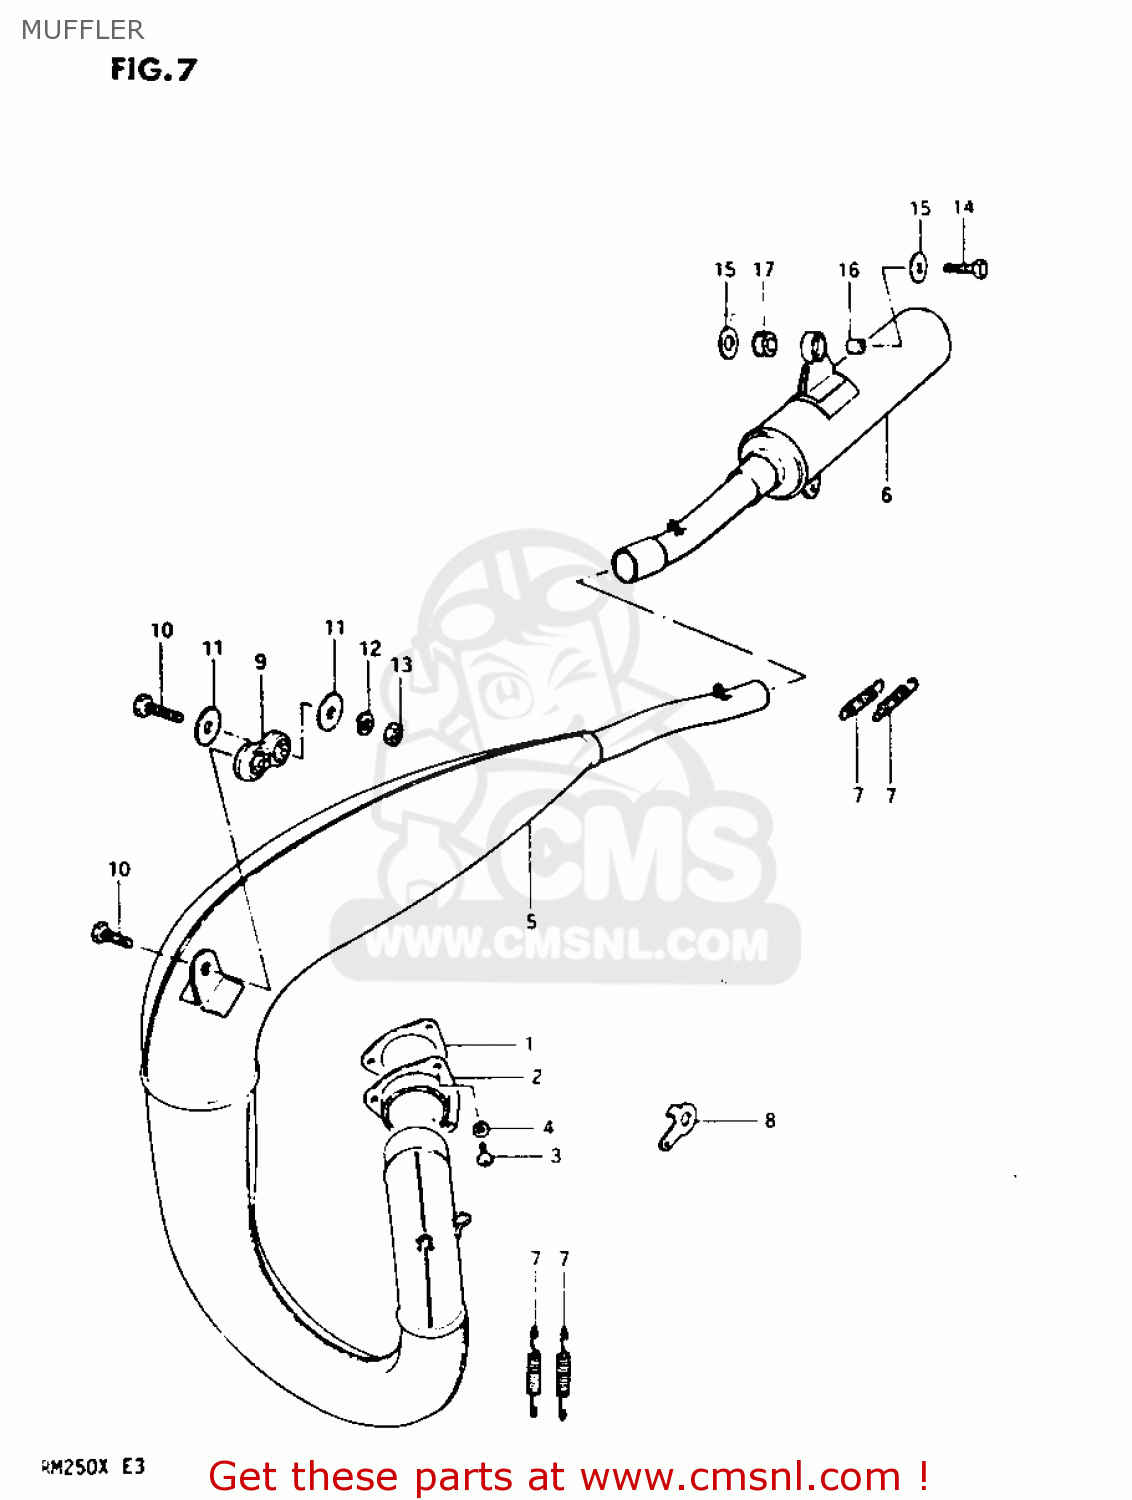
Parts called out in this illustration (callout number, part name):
1	GASKET,EXHAUST PIPE (MCA)
2	FLANGE,EXHAUST PIPE
3	SCREW
4	WASHER,LOCK
5	MUFFLER ASSEMBLY,FIRST
6	BODY,MUFFLER,SECOND
7	SPRING
8	HOOK,MUFFLER FIT SPRING
9	DAMPER,MUFFLER
10	BOLT(8X32)
11	WASHER
12	LOCK WASHER
13	NUT
14	BOLT(8X32)
15	WASHER (8.5X29X1.6)
16	SPACER (8.6X12X17.5)
17	CUSHION
